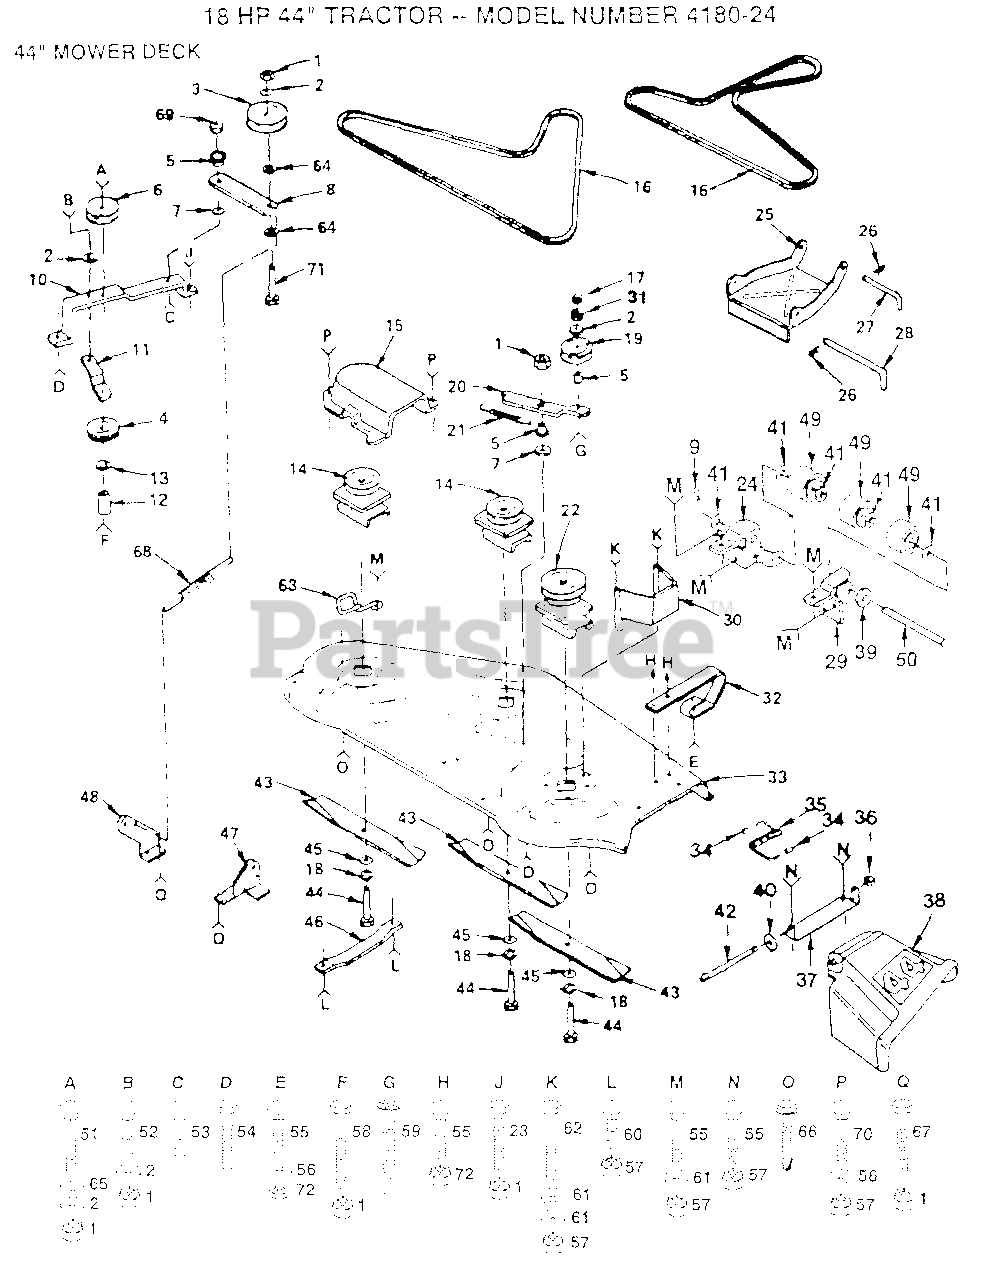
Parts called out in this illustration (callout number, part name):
2	WASHER
3	PULLEY IDLER
4	IDLER-FLAT T
5	SPACER RETAINER
6	IDLER-INSIDE T
7	"WASHER, WEAR LT"
8	ARM IDLER
9	COTTER PIN
10	"SUPPORT YT, BAR"
11	BRACE-IDLER YT
12	SPACER
13	WASHER
15	GUARD YT
16	BELT-V.79.1.MWR
17	NUT.HEX.3/8-16UNC
19	IDLER.FLAT.GTV
20	ARM-IDLER YT
23	BOLT
24	BRACKET LH YTH
25	LINK.PARALLEL
26	SPRING.RETAINER
27	"ROD, FRT. PARAL T"
28	HINGE PIN T
29	BRACKET RH YTH
30	GUARD BELT HYT
31	LOCKWASHER
34	CAP-SLEEVE LT
36	NUT PUSH M
38	DEFLECTOR SHIELD
40	WASHER
41	WASHER T
42	ROD-HINGE T
44	BOLT.3/8-24X1-1/2
45	WASHER
46	RUNNER-LH M
47	BRKT SUSP REAR RH
48	BRKT SUSP REAR LH
49	ROLLER T
50	PIVOT PIN T
51	BOLT
53	BOLT
55	BOLT
56	WASHER
58	BOLT - HEX 3/8 - 16 X 3
59	SCREW YT
60	BOLT
61	WASHER M
62	BOLT
63	BELT RETIANER
64	WASHER
65	WASHER
66	SCREW
67	BOLT
68	"SPRING.EXT.8.5"""
69	LOCKNUT
71	BOLT
